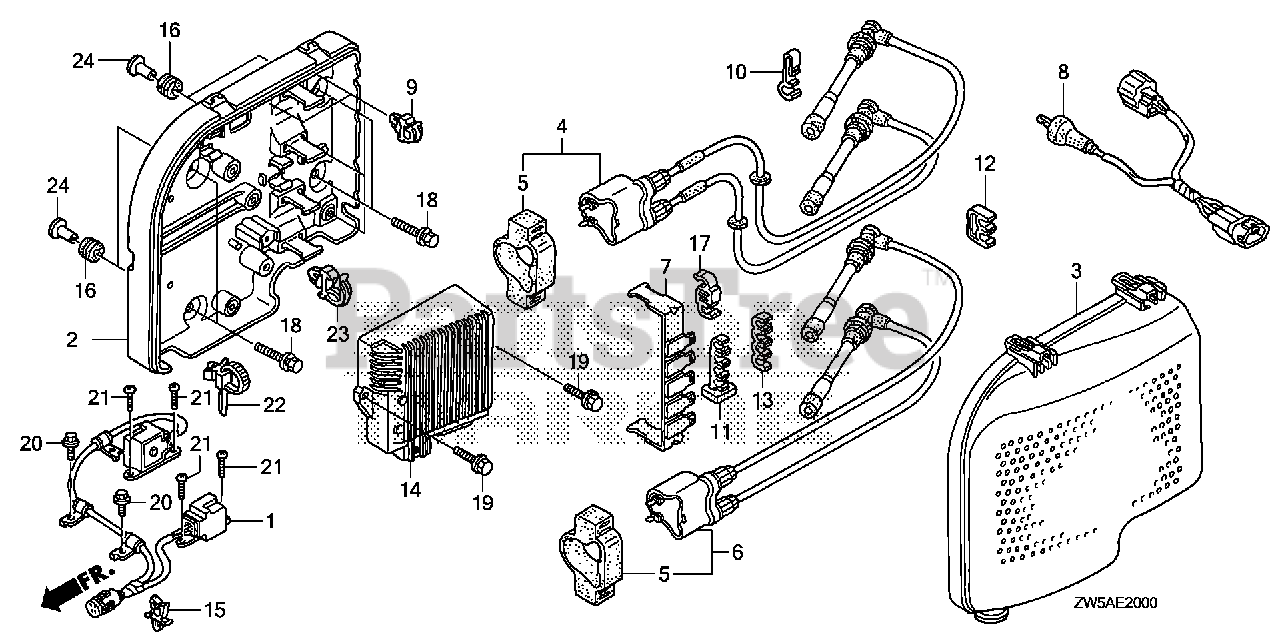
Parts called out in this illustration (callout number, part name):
1	COIL ASSY., PULSER
2	CASE, IGNITION CONTROL MODULE (CDI)
3	COVER, IGNITION CONTROL MODULE (CDI)
4	COIL ASSY., IGNITION (1,4)
5	SUSPENSION, IGNITION COIL
6	COIL ASSY., IGNITION (2,3)
7	BRACKET, CONNECTOR (A)
8	WIRE, SWITCH
9	CLAMP, WIRE
10	CLAMP, WIRE
11	CLAMP A, IGNITION WIRE
12	CLAMP B, IGNITION WIRE
13	GROMMET, IGNITION WIRE
14	CONTROL UNIT, ELECTRONIC
15	CLIP B, AIR TEMPERATURE SWITCH WIRE
16	GROMMET, CASE (LOWER)
17	CLIP A, WATER VALVE SOLENOID
18	BOLT-WASHER (6X27) (CT200)
19	BOLT, FLANGE (6X16)
20	BOLT, FLANGE (6X12)
21	SCREW, PAN (5X14)
22	STRAP, CABLE (118MM) (BLACK)
23	CLIP, WIRE HARNESS
24	COLLAR, MODULE IGNITION CONTROL CASE (CDI)
